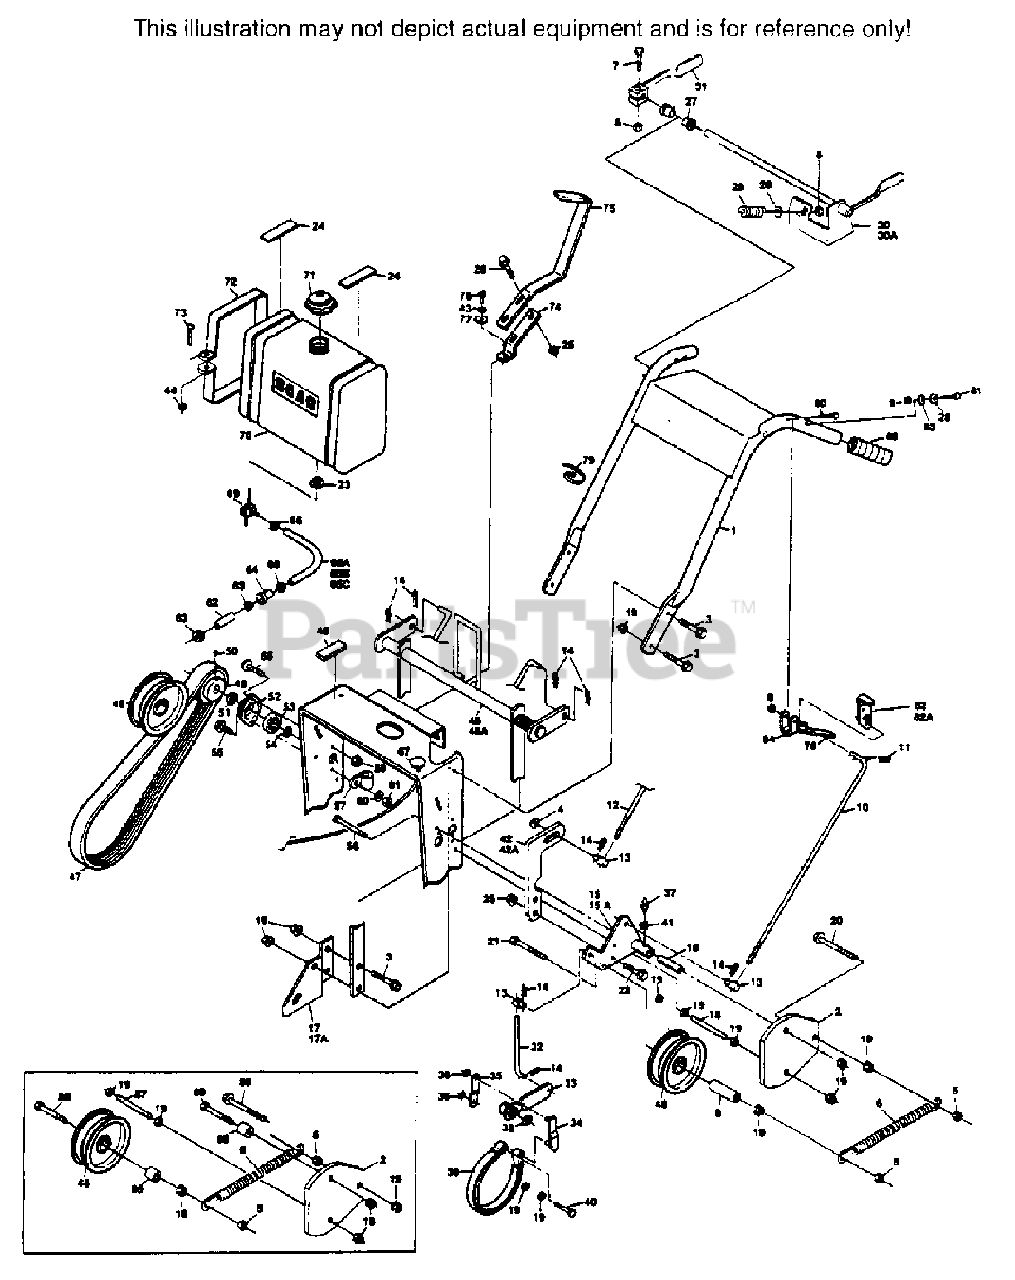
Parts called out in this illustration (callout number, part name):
1	HANDLE ASSEMBLY(FITS SW 32, 36, 48)
1	HANDLE ASSEMBLY(FITS SW 52, 61, 72)
2	BELT GAURD
3	CAPSCREW, 3/8-16 X 1" SERRATED FLANGE
4	WASHER, 25/64 X 15/16 X 12 GA.
5	HEX NUT, 3/8-16 ELASTIC STOP
6	SPRING, IDLER
8	HEX NUT 5/16-18 ELASTIC STOP
9	SPACER, IDLER SPRING
10	CONTROL ROD, STEERING
11	HAIR PIN, SMALL
12	ROD, TRACTION CONTROL
13	SWIVEL JOINT
14	HAIR PIN, LARGE
15	IDLER BRACKET, RH
15A	IDLER BRACKET, LH
16	IDLER SLEEVE
17	MOUNTING BRACKET, TRACTION CONTROL, LH
17A	MOUNTING BRACKET, TRACTION CONTROL, RH
18	SUPPORT BELT GUARD
19	NUT, 3/8-16, SERRATED FLANGE
20	CAPSCREW, 3/8-16 X 2" SERRATED FLANGE
22	CAPSCREW, 5/16-18 X 3/4" SERRATED FLANGE
23	BUSHING
24	RUBBER PADS,(UPPER)
25	NUT, 5/16-18 SERRATED FLANGE
26	CAPSCREW, 5/16-18 X 1" SERRATED FLANGE
27	BUSHING
29	SPRING, OPERATOR'S PRESENCE
30	OPERATOR'S PRESENCE LEVER, LH(SMALL FRAME)
30A	OPERATOR'S PRESENCE LEVER, LH(LARGE FRAME)
31	OPERATOR'S PRESENCE LEVER, RH
32	BRAKE ROD
33	BRAKE LEVER
34	BRAKE LINK
35	BRAKE LINK PLATE
36	NUT, 3/8 PUSH-ON
37	GREASE FITTING, STRAIGHT, 1/4-28
38	RETAINING RING, 5/8 EXT.-"E"
39	BRAKE BAND
41	1/4" INTERNAL TOOTH LOCKWASHER
42	TRACTION LEVER, LH
42A	TRACTION LEVER, RH
43	LOCKWASHER, 1/4 SPRING
45	TRACTION LEVER WELDMENT(SMALL FRAME)
45A	TRACTION LEVER WELDMENT(LARGE FRAME)
46	RUBBER PAD(LOWER)
47	BELT, WHEEL DRIVE
48	IDLER PULLEY, WHEEL DRIVE
49	PULLEY, JACKSHAFT(INCLUDES 50)
51	SPACER, JACKSHAFT PULLEY
52	FLANGE, JACKSHAFT BEARING
53	BEARING, JACKSHAFT
54	RETAINING RING, 5/8 EXT.-BASIC
55	CAPSCREW, 1/4-20 X 1" SERRATED FLANGE
58	CAPSCREW, 5/16-18 X 3/4 SERRATED FLANGE
59	NUT, 1/4-20 SERRATED FLANGE
61	1/4-20 ELASTIC STOP NUT
65	FUEL HOSE 1/4" ID, 10"(KOHLER ONLY)
66	CLAMP, FUEL HOSE
68	GRIP, HANDLE
69	VALVE, FUEL SHUT OFF
70	FUEL TANK ASSEMBLY(INCLUDES BUSHING & VALVE)
71	FUEL TANK CAP
72	STRAP, FUEL TANK
73	MACHINE SCREW, 1/4-20 X 2 ROUND HEAD SLOTTED
74	SHIFTER LEVER
75	SHIFTER LEVER EXTENSION
76	GRIP, STEERING LEVER
77	WASHER, 17/64 X 7/8 X 1/8 HT
78	HEX HEAD BOLT, 1/4-28 X 3/4 GRADE 8
79	CABLE TIE
82	NEUTRAL LATCH, RH
82A	NEUTRAL LATCH, LH
83	CURVED SPRING WASHER
84	STEERING LEVER(INCLUDES GRIP)
85	SPACER
86	CAPSCREW, 3/16 X 1-1/4 SERRATED FLANGE
87	STUD, 3/8-16 X 5"
